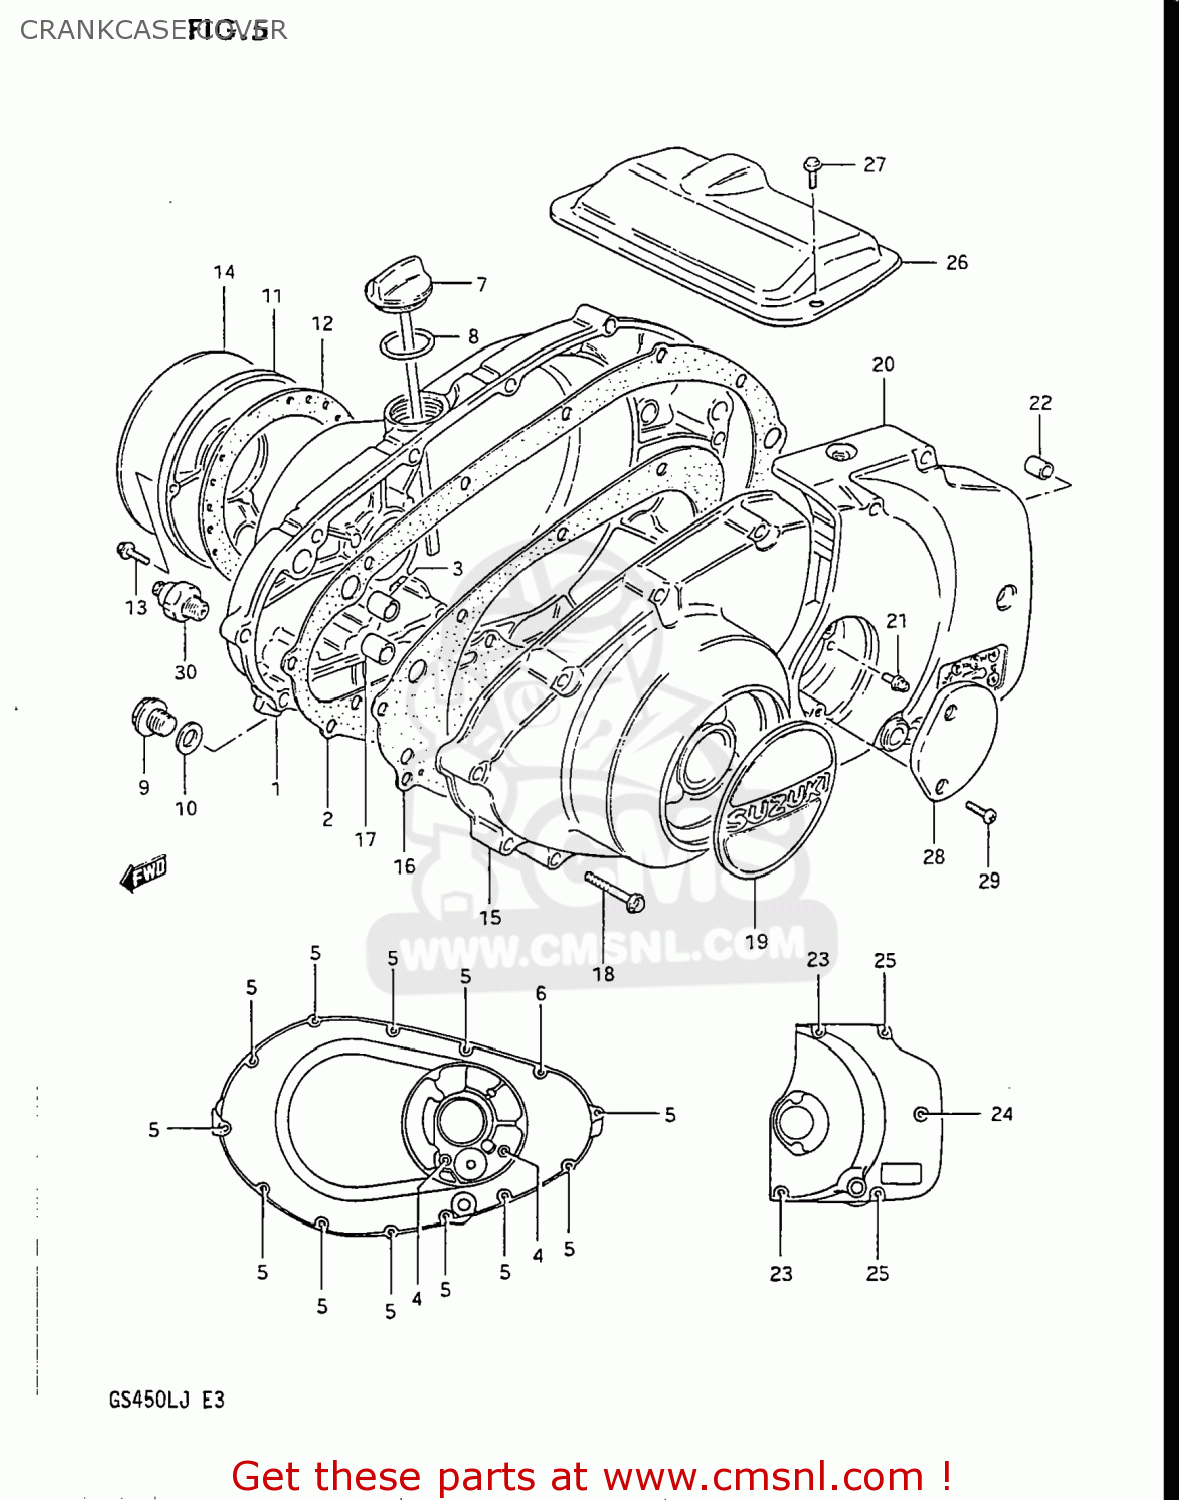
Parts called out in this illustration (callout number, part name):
1	COVER,CLUTCH
2	GASKET,CLUTCH COVER (MCA)
3	PIN
4	BOLT (6X55)
5	BOLT (6X35)
6	BOLT
7	GAUGE,OIL LEVEL
8	O-RING
9	PLUG (14X12)
10	GASKET(14X19.2X2) (NAS)
11	COVER,CONTACT BREAKER
12	GASKET,CONTACT BREAKER COVER (NAS)
13	BOLT 5X16
14	EMBLEM,MAGNETO COVER
15	COVER,MAGNETO
16	GASKET,MAGNETO COVER (MCA)
17	PIN
18	BOLT (6X35)
19	EMBLEM,MAGNETO COVER
20	COVER,ENGINE SPROCKET
21	NIPPLE
22	PIN
23	BOLT
24	BOLT
25	BOLT (6X40)
26	COVER,STARTER MOTOR
27	BOLT
28	CAP,CLUTCH RELEASE ADJUST
29	SCREW 5X12
30	SWITCH ASSEMBLY
